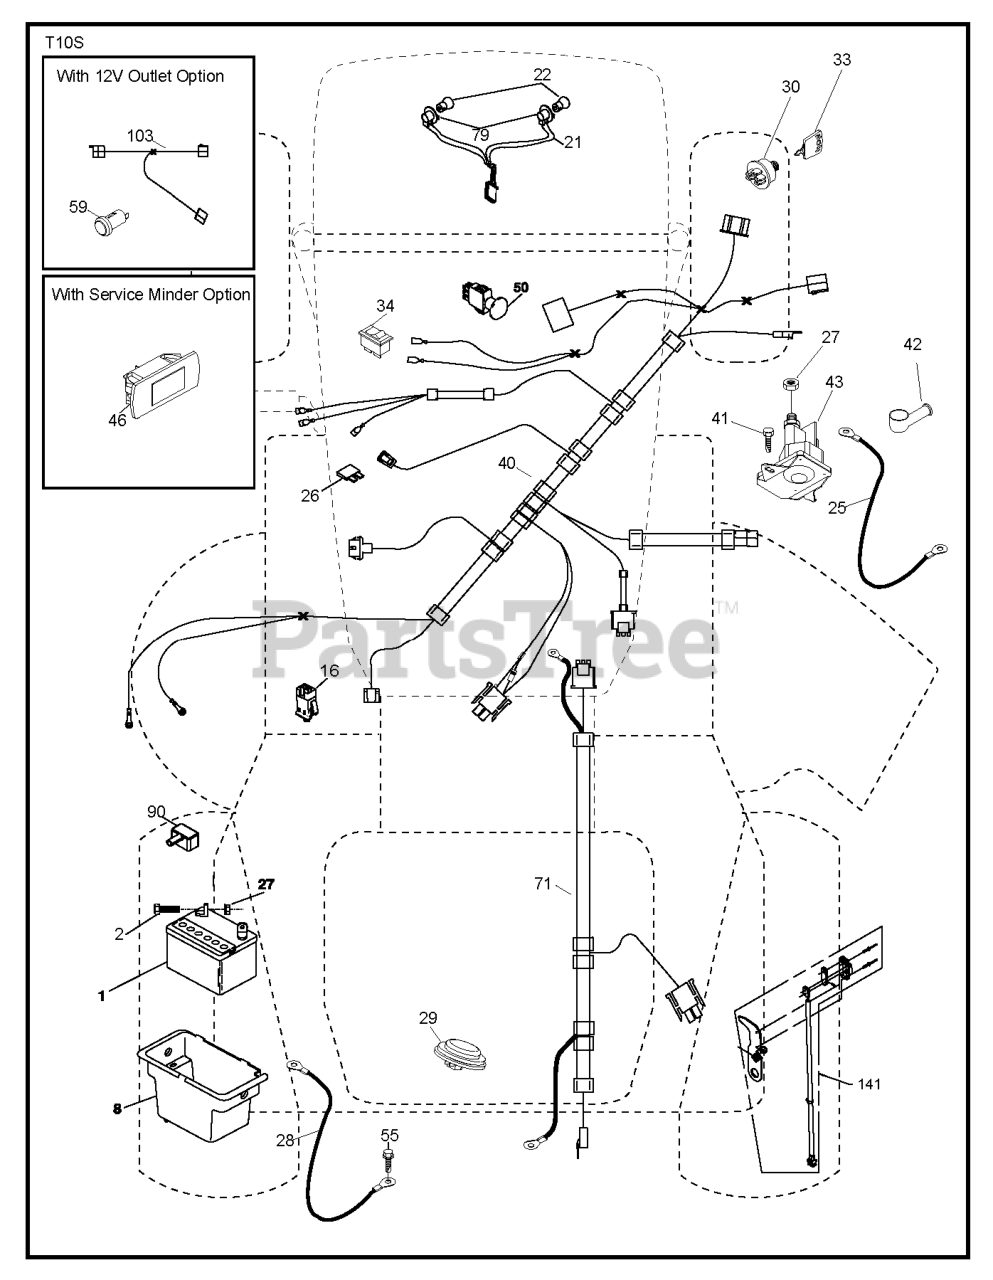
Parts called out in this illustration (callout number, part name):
1	SCREW #10 X 1/2 SELF TAPPING
3	FUSE, 7.5 AMP 32 VOLT ATO
4	FUSE, 20 AMP 32 VOLT ATO
5	SWITCH, INTERLOCK
6	IGNITION SWITCH KIT
7	RP.SWITCH, BLADE
8	DIGITAL HOUR METER
9	SCREW #10-24 X 5/8
10	TAPPED PLATE
11	CONSOLE HARNESS
12	NUT 1/4C CENTERLOCK
13	HCS 1/4C X 5/8
14	POST.CABLE LONG
15	FRAMES HARNESS
16	CABLE POSITIVE, LONG
17	HCS 5/16C X 3/4
19	NUT 5/16C CENTERLOCK
20	CABLE-NEGATIVE
21	BATTERY WET NOT SELLABLE
22	NUT 10-24 NYLOC
23	KEY-PADDED
24	CAP IGNITION NUT
25	DNO IGNITION NUT
26	KOH PIGTAIL
27	KAW PIGTAIL
28	SCREW, #1--24 X 1/2 SLOTTED
30	WASHER 1/4 INT TOOTH
539102757	CABLE POSITIVE
